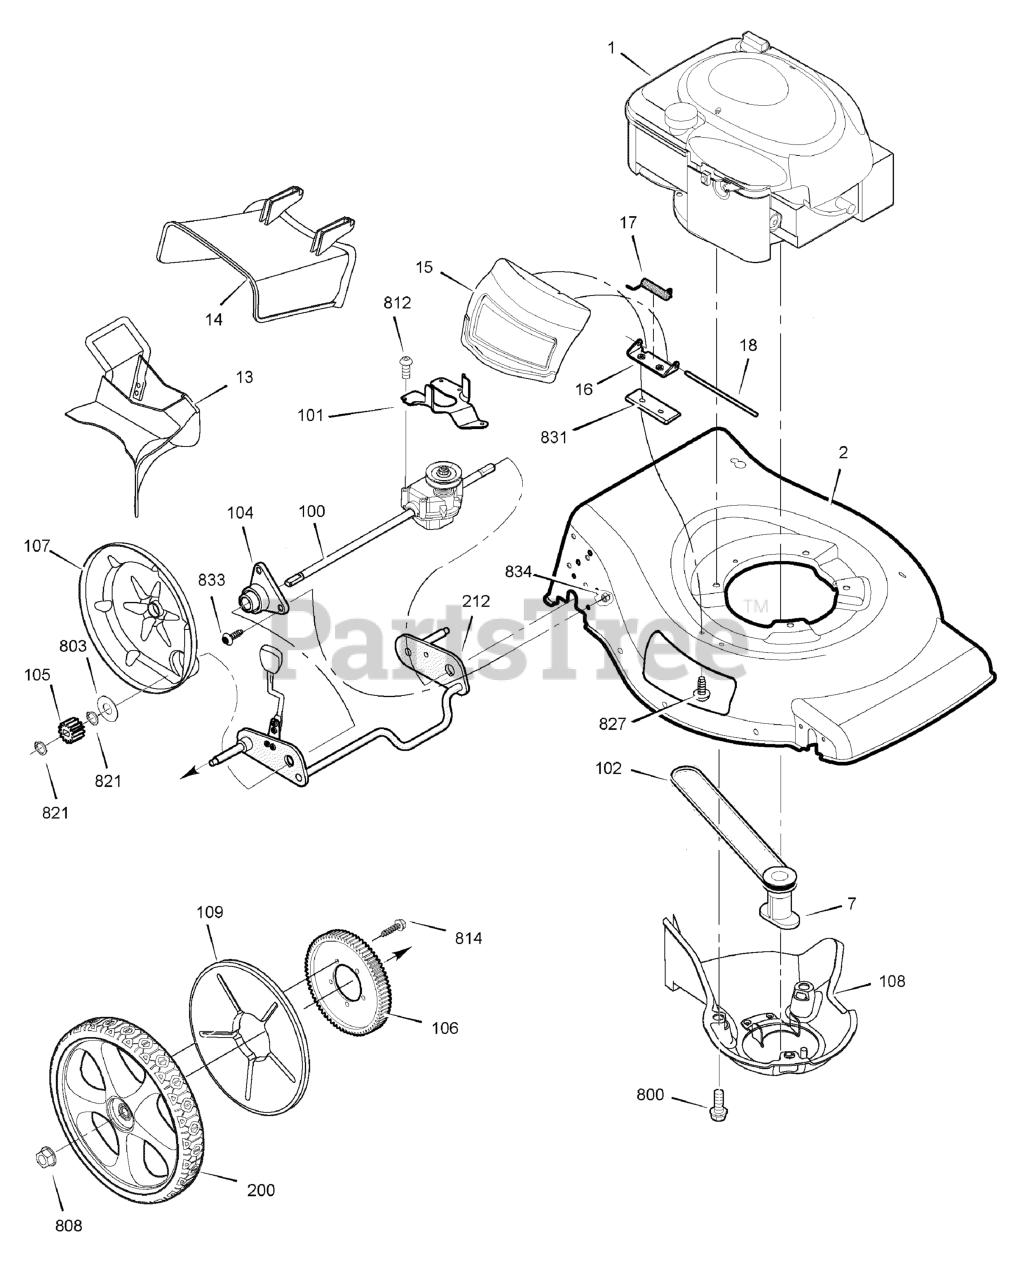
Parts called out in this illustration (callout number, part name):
1	* ENGINE
2	MOWER HOUSING
7	BLADE ADAPTER ASSEMBLY
13	MULCH PLUG
14	CHUTE DEFLECTOR
15	MULCH COVER
16	BRACKET, Chute Deflector
17	SPRING, Chute Deflector
18	ROD, Chute Deflector
100	TRANSMISSION
101	BELT GUIDE, Transmission
102	V-BELT
104	SLEEVE ASSEMBLY, Rear Axle
105	GEAR, Pinion
106	GEAR, Drive
107	DUST COVER
108	BELT COVER ASSEMBLY
109	COVER, Wheel
200	WHEEL, Rear
212	CROSSBAR ASSEMBLY, Rear
800	SCREW, Hex Head, 3/8-16 x 1
803	WASHER, Thrust
808	NUT, Flange, 3/8-16
812	SCREW, #10 x 1
814	SCREW, 1/4-15 x 3/4
821	RING, External Retaining
827	SCREW, 1/4-20 x 7/8
834	NUT, Flange Lock, 1/4-20
